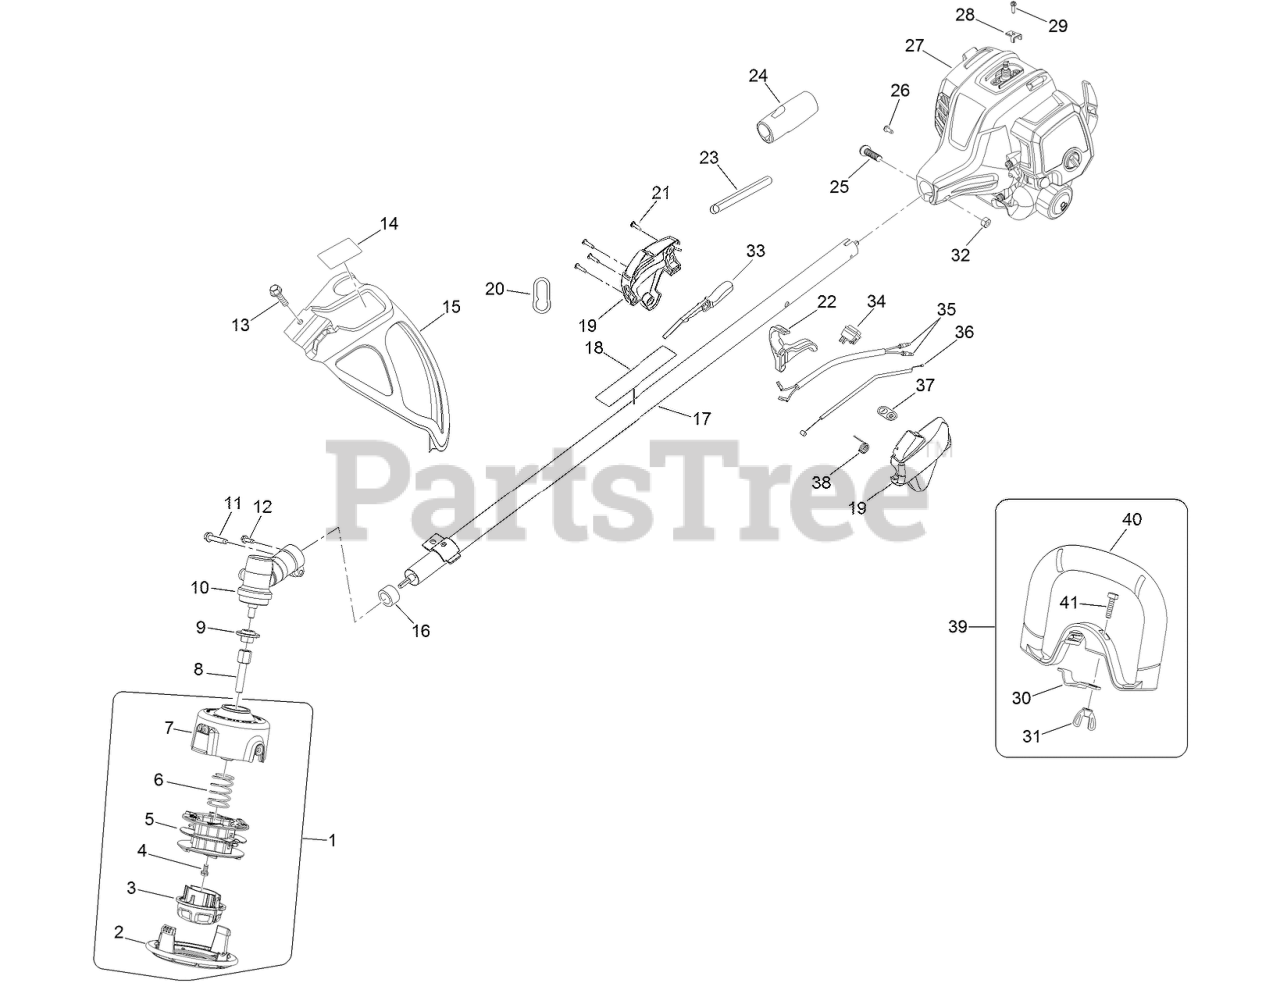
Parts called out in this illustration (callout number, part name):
1	TRIMMER HEAD ASM
2	HOUSING-STRINGHEAD, LOWER
3	KNOB-BUMP
5	SPOOL ASM
6	SPRING-COMPRESSION
7	HOUSING-SPOOL, STRAIGHT SHAFT
8	ADAPTOR-HEAD SHAFT, TRIMMER
9	WASHER-FLANGE
10	GEAR CASE ASM
13	SCREW-HWH
14	LABEL-DEFLECTOR, GRASS
15	GRASS DEFLECTOR ASM
17	UPPER BOOM ASM (INCLUDES ITEM 18)
18	DECAL-WARNING
19	CONTROL HANDLE ASM
20	CLIP-STRAP, SHOULDER
22	TRIGGER
23	TUBE-CORRUGATED
24	GRIP-SHAFT, UPPER
27	POWERHEAD ASM
28	CLAMP-CABLE, THROTTLE
30	CLAMP-HANDLE, UPPER SHAFT
31	NUT-WING
32	NUT-HEX
33	TRIGGER LOCK
34	SWITCH-ON/OFF
36	CABLE-THROTTLE
37	LABEL-ON/STOP
38	SPRING-TRIGGER
39	HANDLE ASM
40	HANDLE-SHAFT, UPPER
